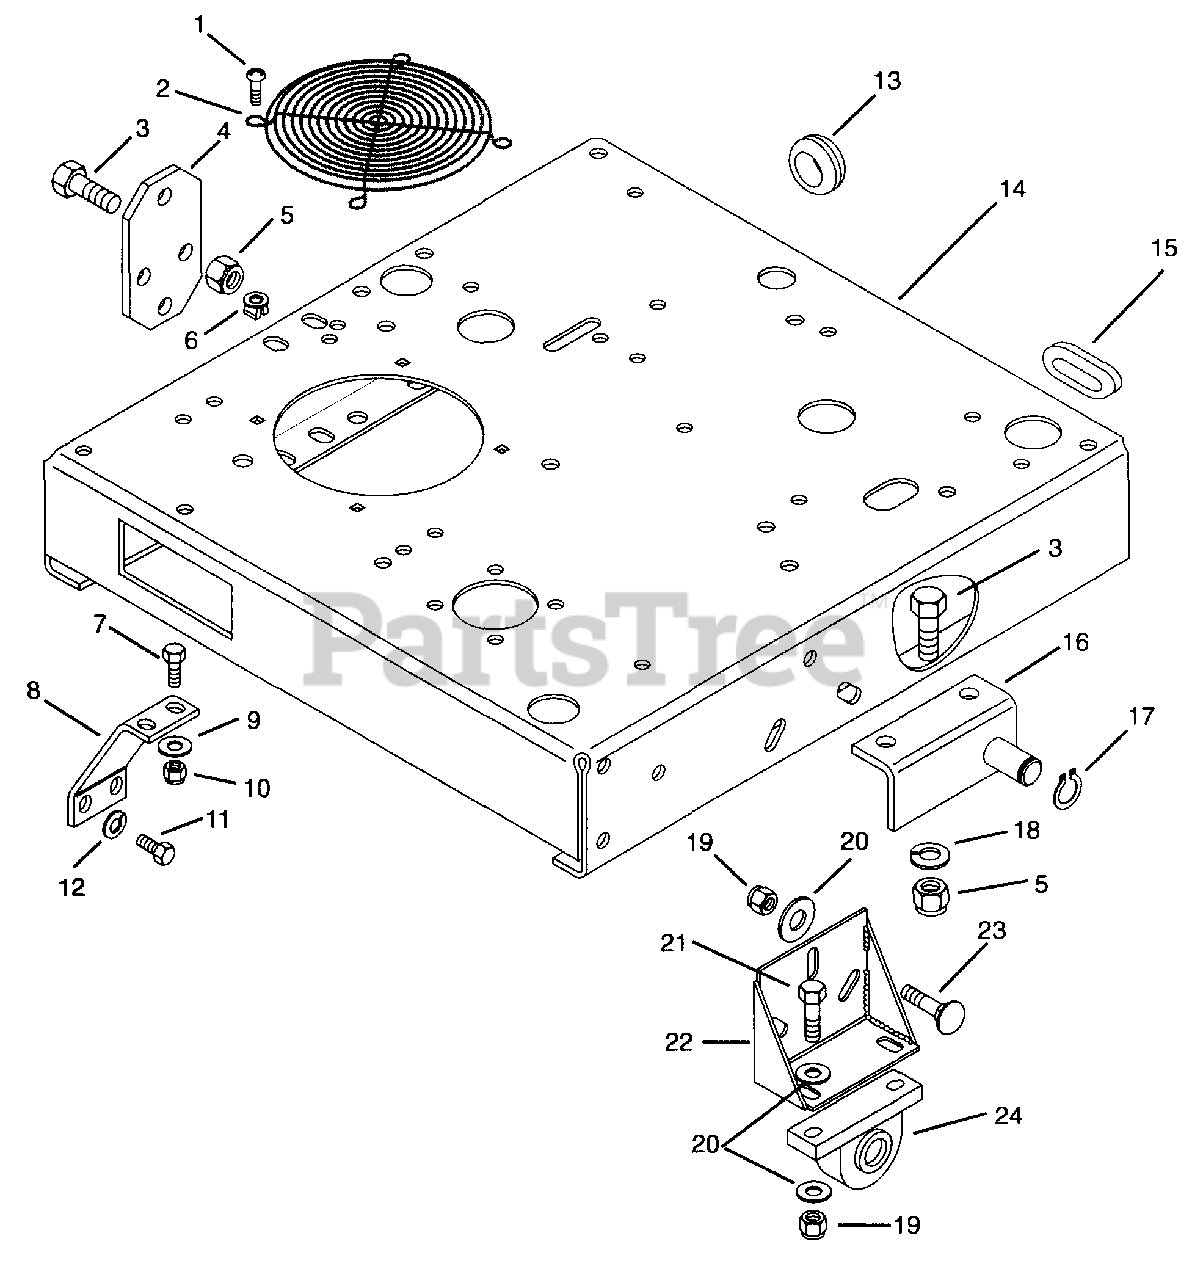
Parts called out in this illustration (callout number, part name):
1	Screw-Tapping .25-20 x .50
2	Guard Fan
3	Bolt-Hex .50-13 x 1.50 Grade 5
4	Plate
5	Nut-Locking-Center .50-13
6	Grommet, Plastic
7	Bolt-Hex .38-16 x 1.00 Grade 5
8	Bracket, Transaxle Support
9	Washer-Flat-Steel .344 x .688 x .065
10	Nut-Locking-Center .31-18
11	Bolt-Hex .31-18 x .75 Grade 5
12	Washer-Lock .31 x .078
13	Grommet 1.50 x 1.75 x 2.12
14	Weldment, Frame
15	Grommet .63 x .687 x 1.25
16	Weldment, Pivot Left Hand
16	Weldment, Pivot Right Hand
17	Ring-Retaining-External .689 x .077
18	Washer-Lock .50 x .125
19	Nut-Locking-Center .38-16
20	Washer-Flat-Steel .406 x .812 x .065
21	Bolt-Hex .38-16 x 1.50 Grade 5
22	Weldment, Axle Support
23	Bolt-Round Head Square Neck .38-16 x 1.00
24	Bearing, Pillow Block 1.0 x 2.688 x 6.188
